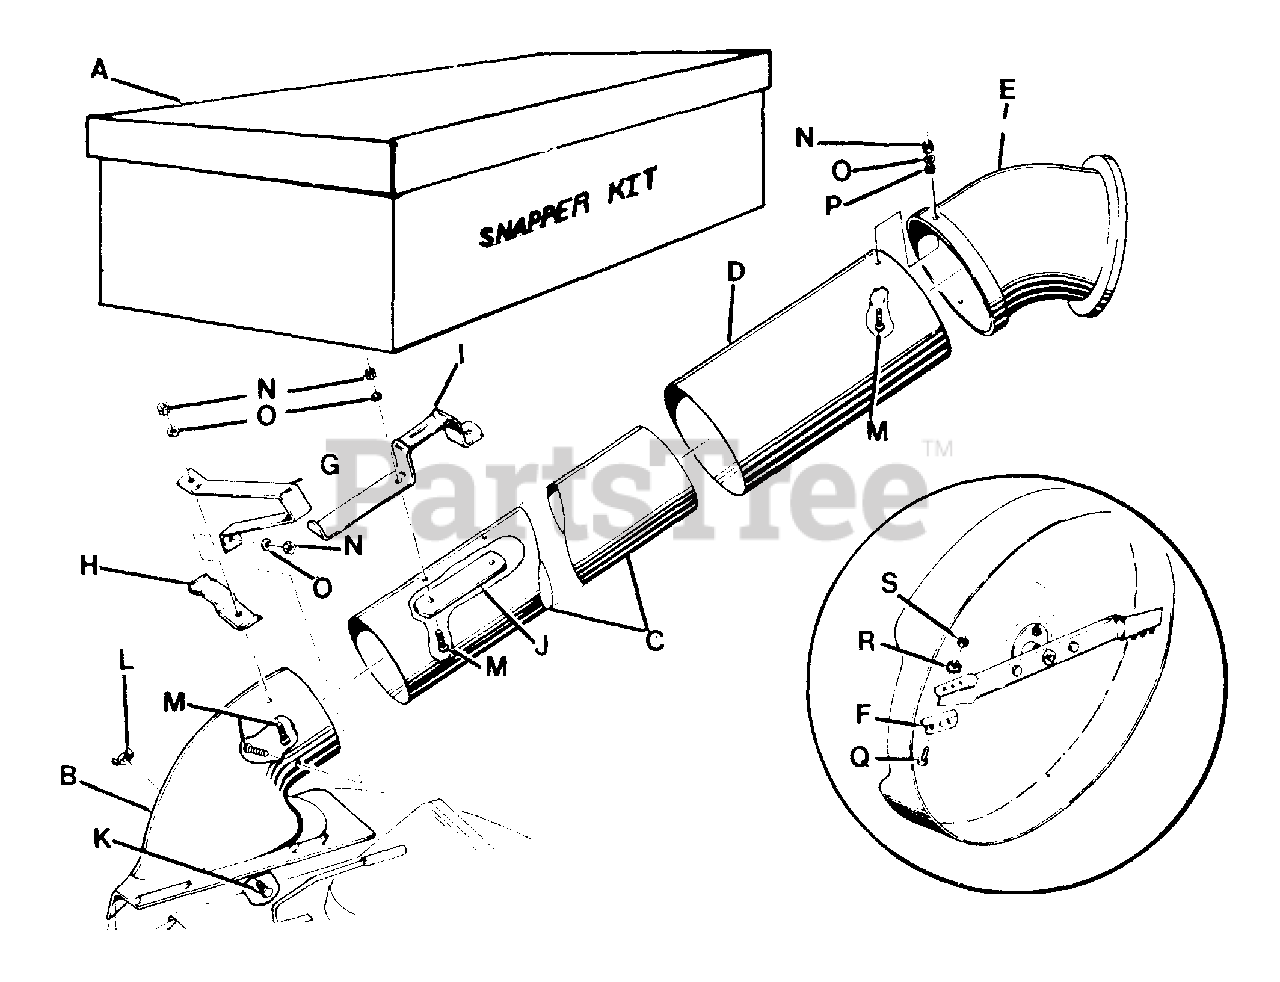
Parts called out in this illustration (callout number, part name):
A	KIT, SNAPPER BAG-N-WAGON
B	ADAPTER, DECK
C	TUBE, GRASS - 8" DIAMETER
D	TUBE, GRASS - 10" DIAMETER
E	ELBOW, GRASS TUBE
F	AIR-LIFT, BLADE
G	BRACKET, STAND-OFF
H	LATCH, TUBE
I	HANDLE, TUBE
J	BASE, TUBE HANDLE
K	BOLT, CARRIAGE 5/16-18x1/2
L	WING-NUT, 5/16-18
M	BOLT, CARRIAGE 1/4-20x3/4
N	NUT, 1/4-20 HEX
O	WASHER, 1/4 INTERNAL TOOTH LOCK
P	WASHER, 5/16 SAE
Q	SCREW OH MACHINE 5/16-24x21/32
R	WASHER, 5/16 INTERNAL TOOTH LOCK
S	NUT, 5/16-24 HEX
